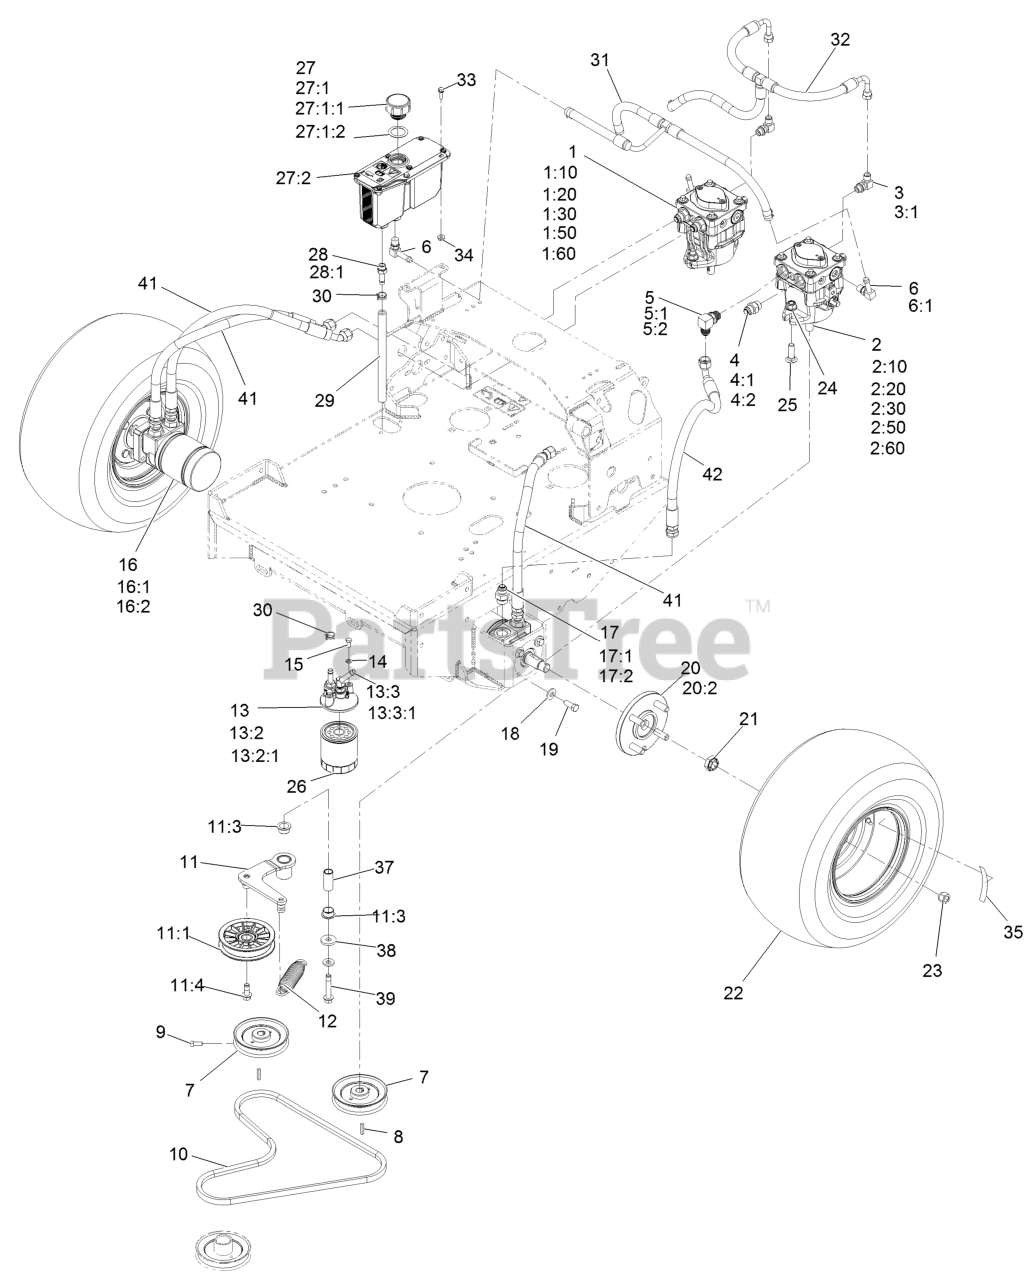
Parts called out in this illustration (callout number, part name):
1	Pump-HYD Pe RH TTH
1:10	Input Shaft Kit
1:20	Bearing-Thrust
1:30	Cylinder Block Kit
1:50	Seal Overhaul Kit
1:60	Kit, 10Cc Pump Kit
2	Pump-HYD Pe LH TTH
2:10	Input Shaft Kit
2:20	Bearing-Thrust
2:30	Cylinder Block Kit
2:50	Seal Overhaul Kit
2:60	Kit, 10Cc Pump Kit
3	Fitting-Elbow, 90 DEG
3:1	O-Ring
4	Adapter-Straight
4:1	O-Ring-SAE #8
4:2	O-Ring-37 Flare #8
5	Elbow-90deg
5:1	O-Ring-SAE #8
5:2	O-Ring-37 Flare #8
6	Fitting-Elbow, 90
6:1	O-Ring
7	Sheave ASM
8	Key-5Mm X 5Mm X 25Mm
9	Screw-Set, SQH 5/16-18 X3/4
10	Belt
11	ASM, Pump Idler
11:1	Pulley-Idler, Flat
11:3	Bushing-Flanged
11:4	Screw-Hfh
12	Spring-Extension
13	ASM, Filter Head
13:2	Adapter-Straight
13:2:1	O-Ring
13:3	Fitting-Barbed, 45 DEG
13:3:1	O-Ring
14	Washer-Lock 1/4 Heavy
15	Screw-HH 1/4-20 X 5/8
16	HYD Motor ASM
16:1	Seal Kit
16:2	Bearing And Seal Kit
17	Adapter-Straight
17:1	O-Ring
17:2	O-Ring-37 Flare #8
18	Washer-Spring Disc 3/8
19	Screw-HH 3/8-16 X 1
20	Wheel Hub ASM
20:2	Stud-Wheel
21	Nut-Lock
22	Tire And Wheel Assy
23	Nut-Lug 1/2-20
24	Nut-HF, NI
25	Bolt-Carriage 7/16-14 X 1 1/2
26	Element, Oil Filter
27	ASM, HYD Reservoir
27:1	Reservoir-HYD
27:1:1	Cap-Reservoir, HYD
27:1:2	Gasket-Cap
27:2	Decal-Warning
28	Adapter-Straight
28:1	O-Ring
29	Hose-Charge
30	Clamp-Hose 11/16
31	Hose, Case
32	Hose, Charge
33	Screw-Machine 1/4-20 X 3/4
34	Nut-Whizlock 1/4-20
35	Decal-Torque Wheel Lug-Hub
37	Pivot, Idler
39	Screw-HHF W/ Patch
41	Hose,Hydraulic W/Cover
42	HYD Hose ASM
